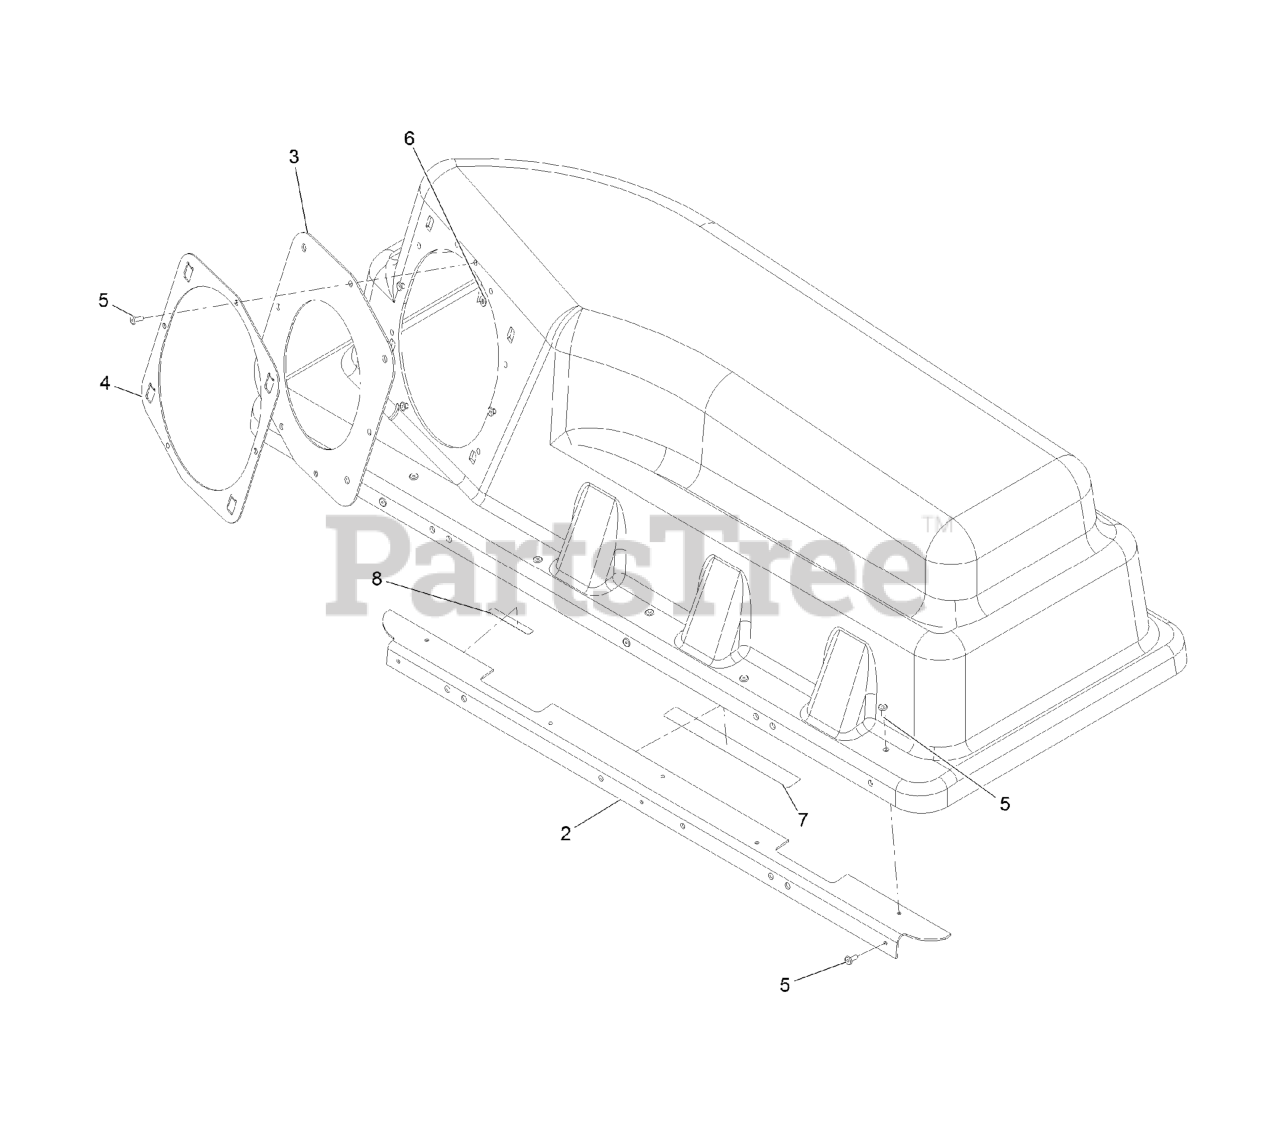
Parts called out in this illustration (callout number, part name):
2	STIFFENER-BAGGER TOP
4	RING-RETAINER
5	RIVET-BLIND
6	WASHER-FLAT
7	DECAL-CAUTION, BAGGER
8	DECAL-WARNING
